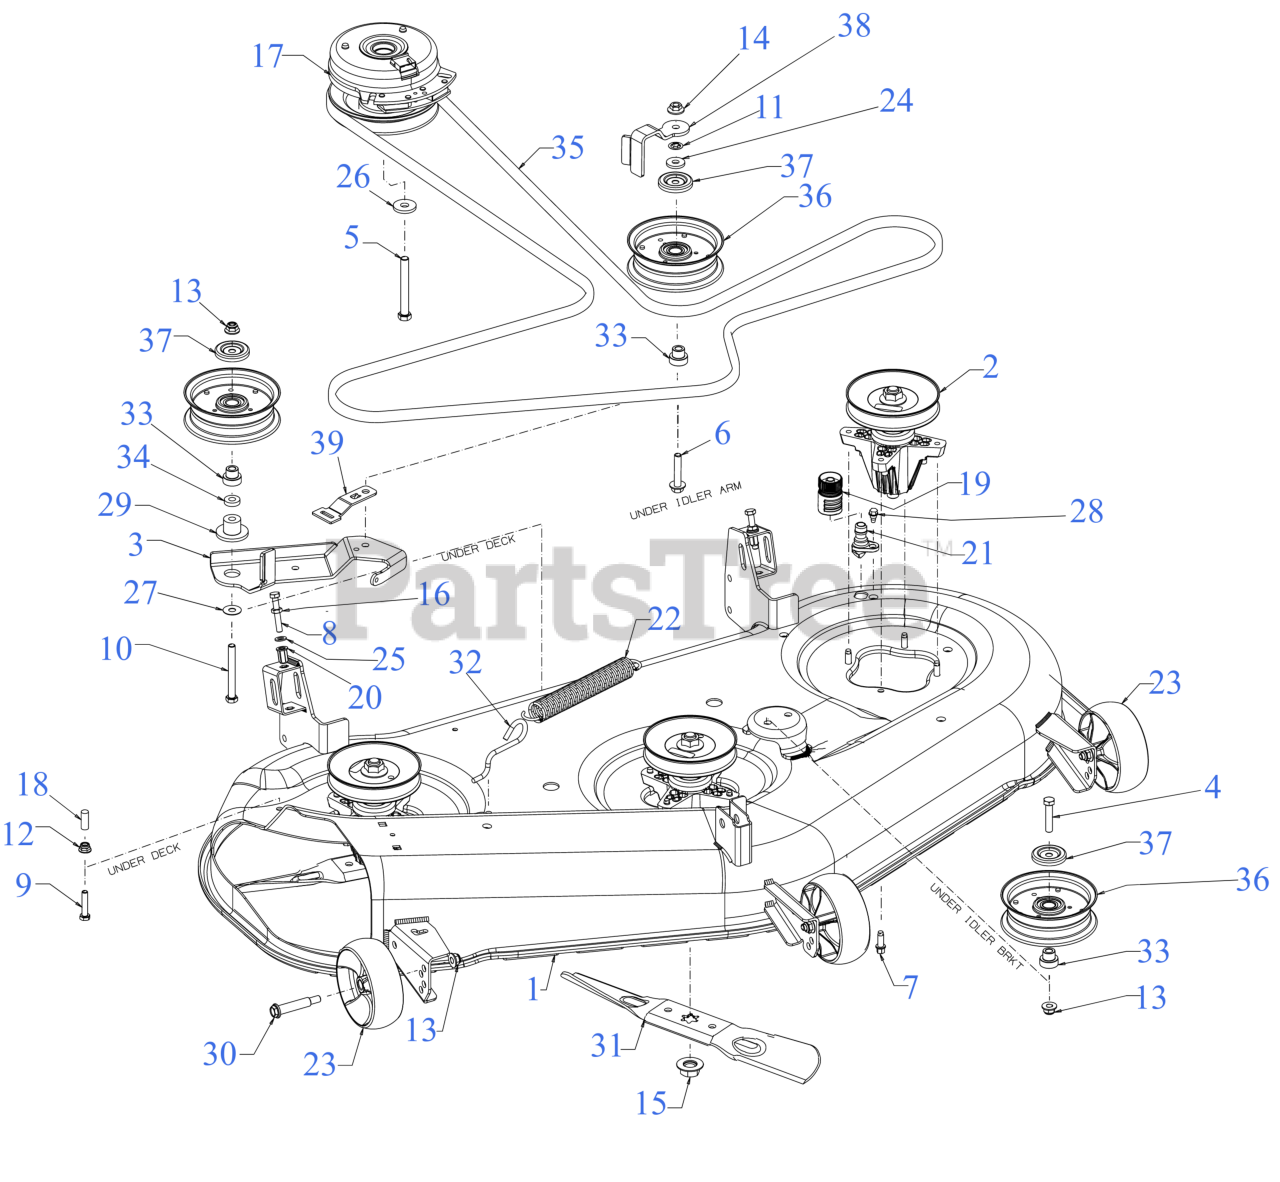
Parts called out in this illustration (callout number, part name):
1	50" DECK SHELL
2	BLADE SPINDLE ASSEMBLY W/PULLEY
2	Cub Cadet 50" SPINDLE ASSEMBLY (06980)
3	DECK IDLER BRACKET
4	HEX SCREW 3/8-16 x 1.75 GR5
5	SCREW 7/16-20 x 3.5 GR5
6	SCREW 3/8-16 x 2.0
7	SCREW 5/16-18 x .875
8	SCREW-FULL THREAD 5/16-18 GR5
9	SCREW 5/16-18 x 1.5 LG
10	SCREW 3/8-16 x 3.25 GR8
12	FLANGE LOCK NUT 5/16-18
14	FLANGE LOCK NUT
15	FLANGE NUT 5/8-18
17	ELECTRIC PTO CLUTCH
19	WATER NOZZLE ADAPTER
20	NUT RIVET 5/16-18
21	DECK WASH NOZZLE
22	EXTENSION SPRING
23	DECK WHEEL (5.0 DIA x 1.875)
23	Cub Cadet 5" DECK WHEEL (06305A) (W/BOLT)
24	FLAT WASHER .385 x 1.00 x .135
25	FLAT WASHER
26	FLAT WASHER .445 x 1.248 x .170
27	FLAT WASHER
28	SHOULDER SCREW 1/4-20 x .50
29	SHOULDER SPACER
30	SHOULDER BOLT (.50 X 2.0 x 3/8 -16)
31	17.27" BLADE (2N1)
31	Cub Cadet 50" HI LIFT BLADE SET
31	Genuine Factory Parts 50" BLADE SET
31	50" 6 PT STAR LOW LIFT/SAND BLADE
31	Cub Cadet 50" LOWLIFT BLADE SET
31	Genuine Factory Parts 50" LOWLIFT BLADE SET
31	50" 6 PT STAR XTREME MULCH BLADE
31	Cub Cadet 50" XTREME BLADE SET
31	Genuine Factory Parts 50" XTREME MULCH BLADE SET
32	DECK SPRING HOOK
33	SHOULDER SPACER
35	V-BELT B SEC x 143.5 LG
35	Cub Cadet 50" DECK DRIVE BELT
35	Genuine Factory Parts 50" DECK BELT
35	Troy-Bilt 50" DECK DRIVE BELT
36	IDLER PULLEY 4.50" DIA
37	IDLER PULLEY CAP
38	BELT KEEPER
